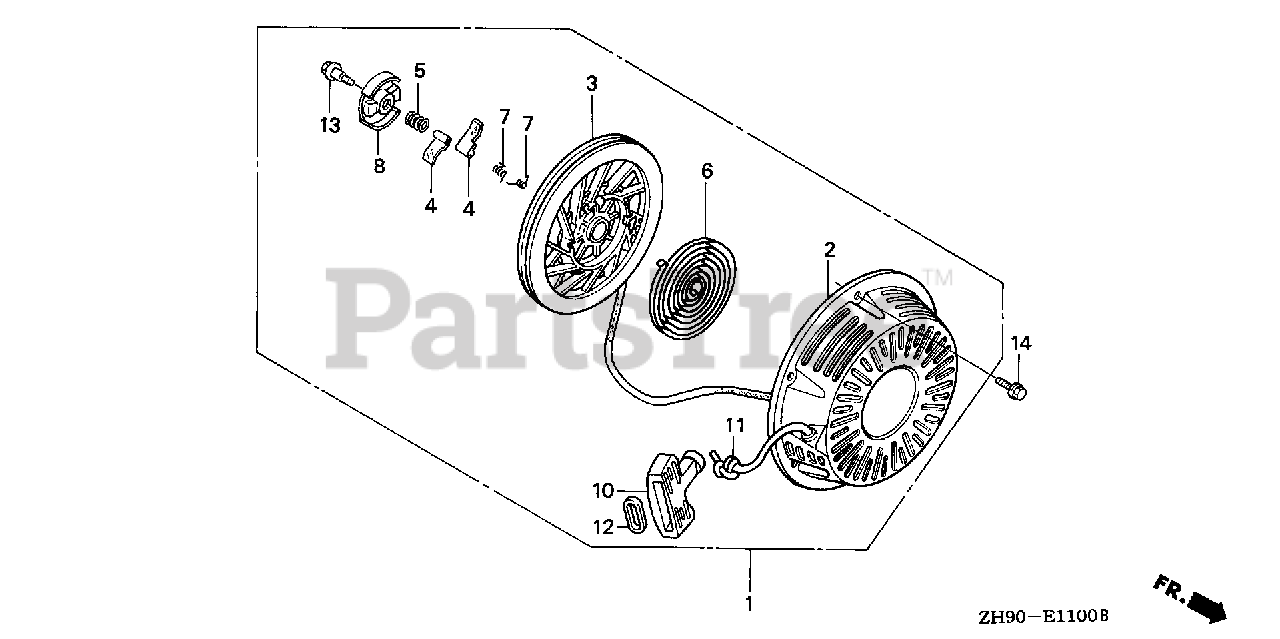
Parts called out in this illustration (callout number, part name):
1	STARTER ASSY., RECOIL *NH105* (MAT BLACK)
2	CASE, RECOIL STARTER *NH105* (MAT BLACK)
3	PULLEY, RECOIL STARTER
4	RATCHET, STARTER
5	SPRING, FRICTION
6	SPRING, STARTER RETURN
7	SPRING, RATCHET
8	RETAINER, SPRING
10	GRIP, STARTER
11	ROPE, RECOIL STARTER (#5X55")
13	SCREW, CENTER
14	BOLT, FLANGE (6X10)
